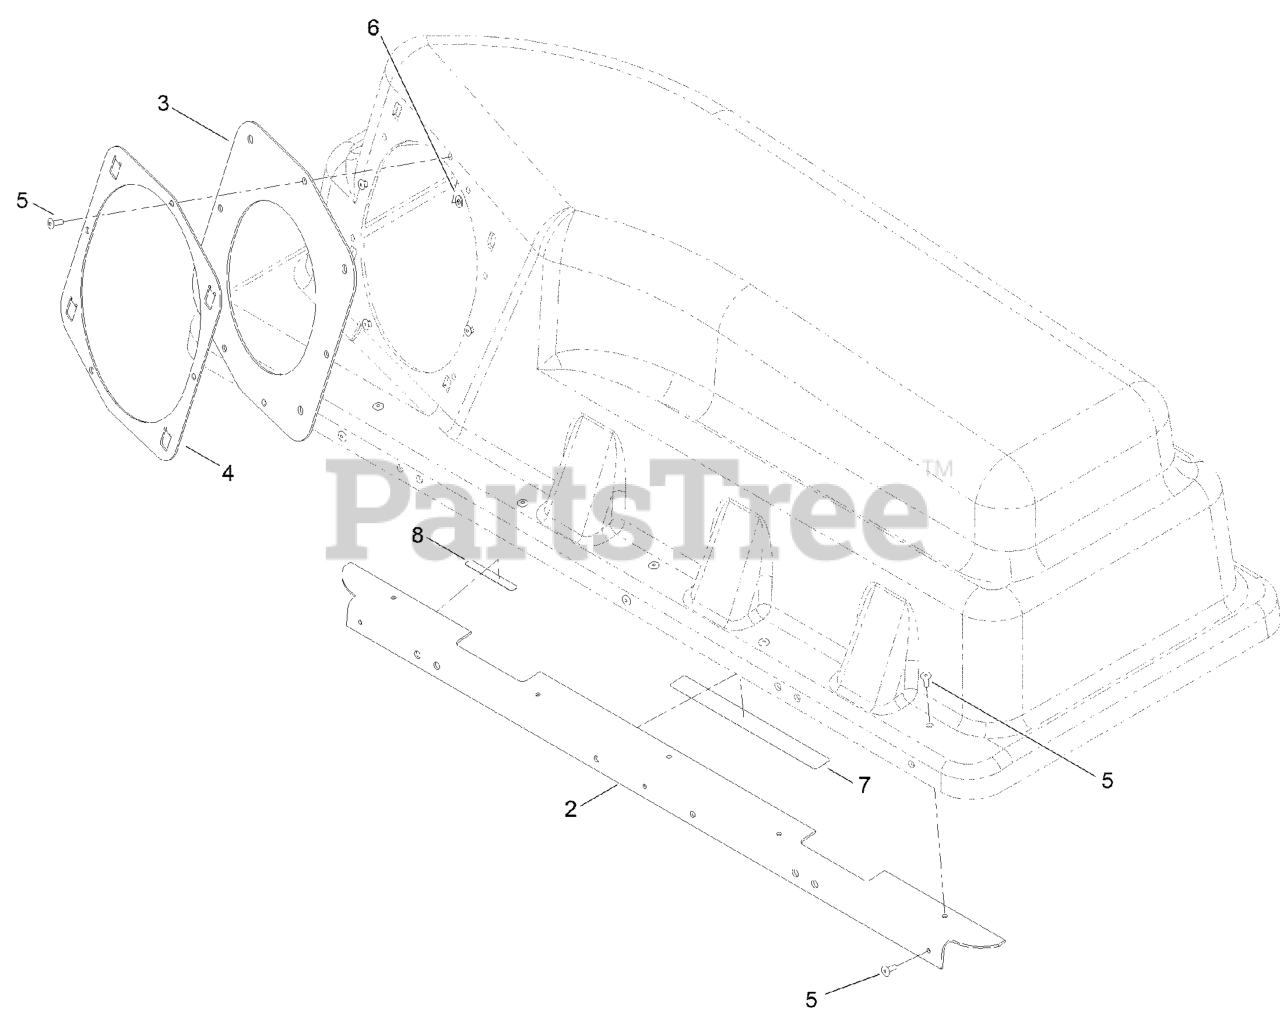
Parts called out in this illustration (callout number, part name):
2	STIFFENER-BAGGER TOP
4	RING-RETAINER
5	RIVET-BLIND
6	Washer-Plain
7	DECAL-CAUTION, BAGGER
8	DECAL-WARNING
